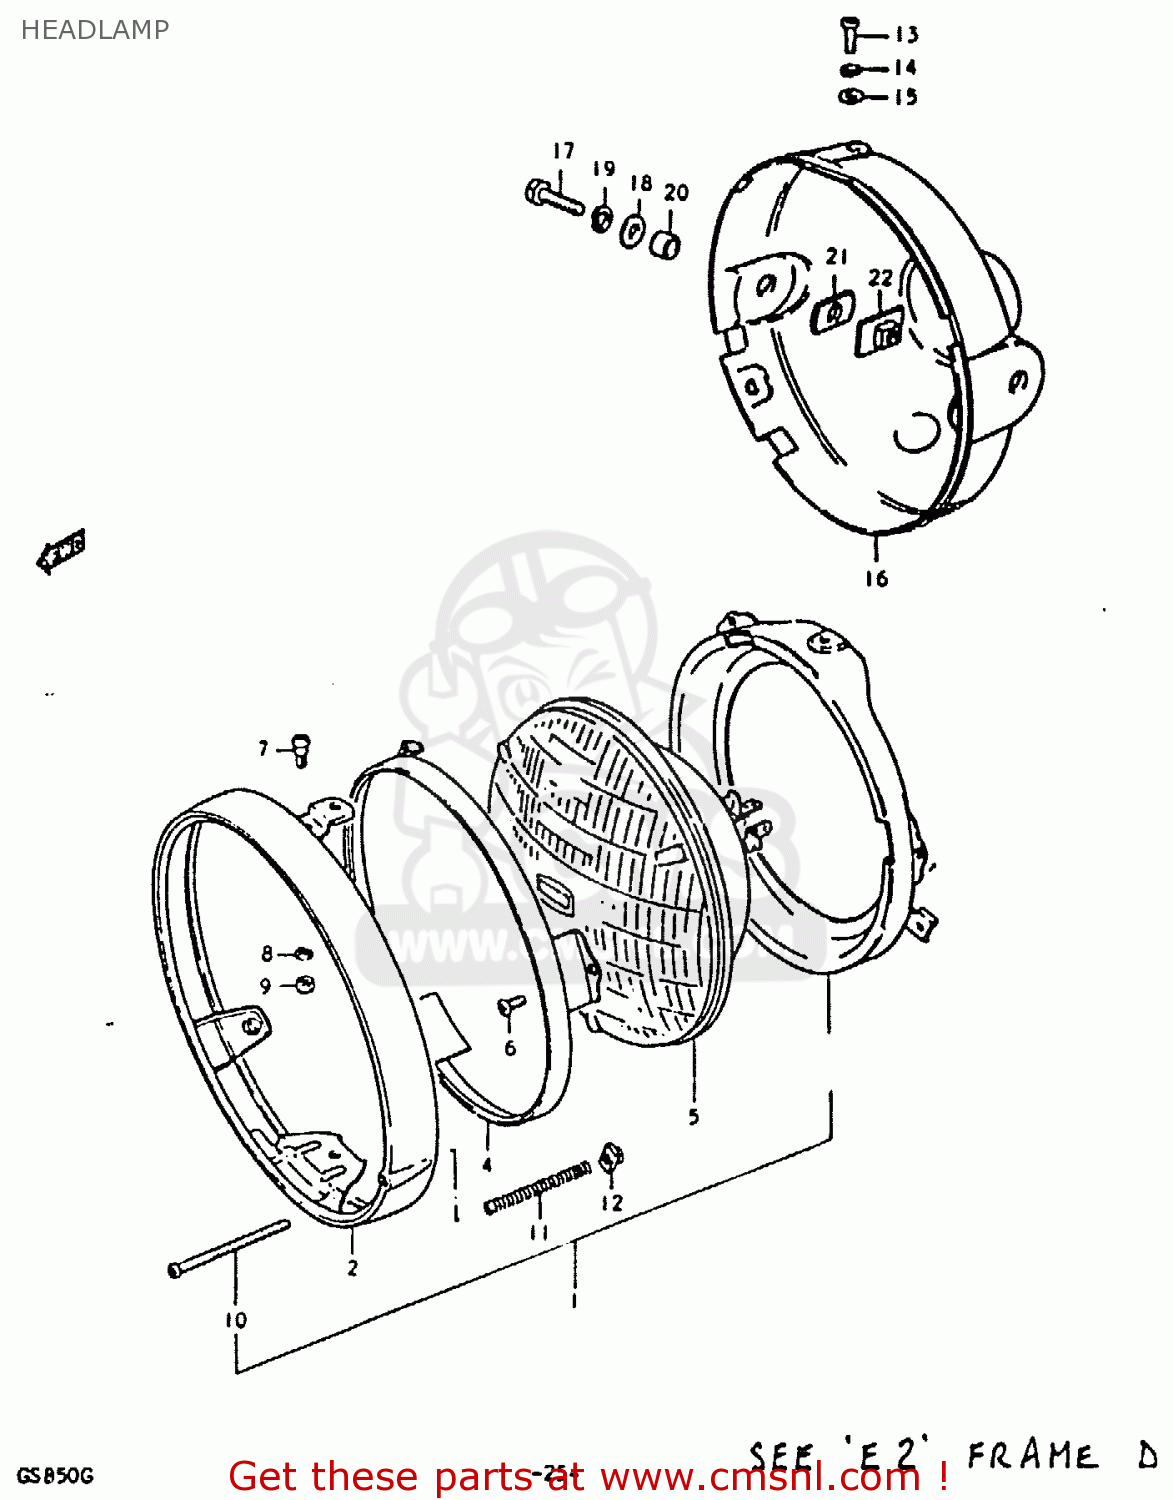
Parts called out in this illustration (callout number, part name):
1	HEADLAMP ASSY
2	RIM
3	RING
4	RETAINING RING
5	UNIT
6	SCREW
7	H/LAMP LENS UNIT FITING SCRE
8	LOCK WASHER
9	NUT
10	SCREW,HEADLAMP ADJUST
11	SPRING,ADJUSTING
12	NUT
13	SCREW
14	WASHER,LOCK
15	WASHER
16	HOUSING,HEADLAMP(BLACK)
17	BOLT
18	WASHER
19	LOCK WASHER
20	SPACER (8.8X12X7)
21	CUSHION
22	PLATE,HEADLAMP HOUSING
